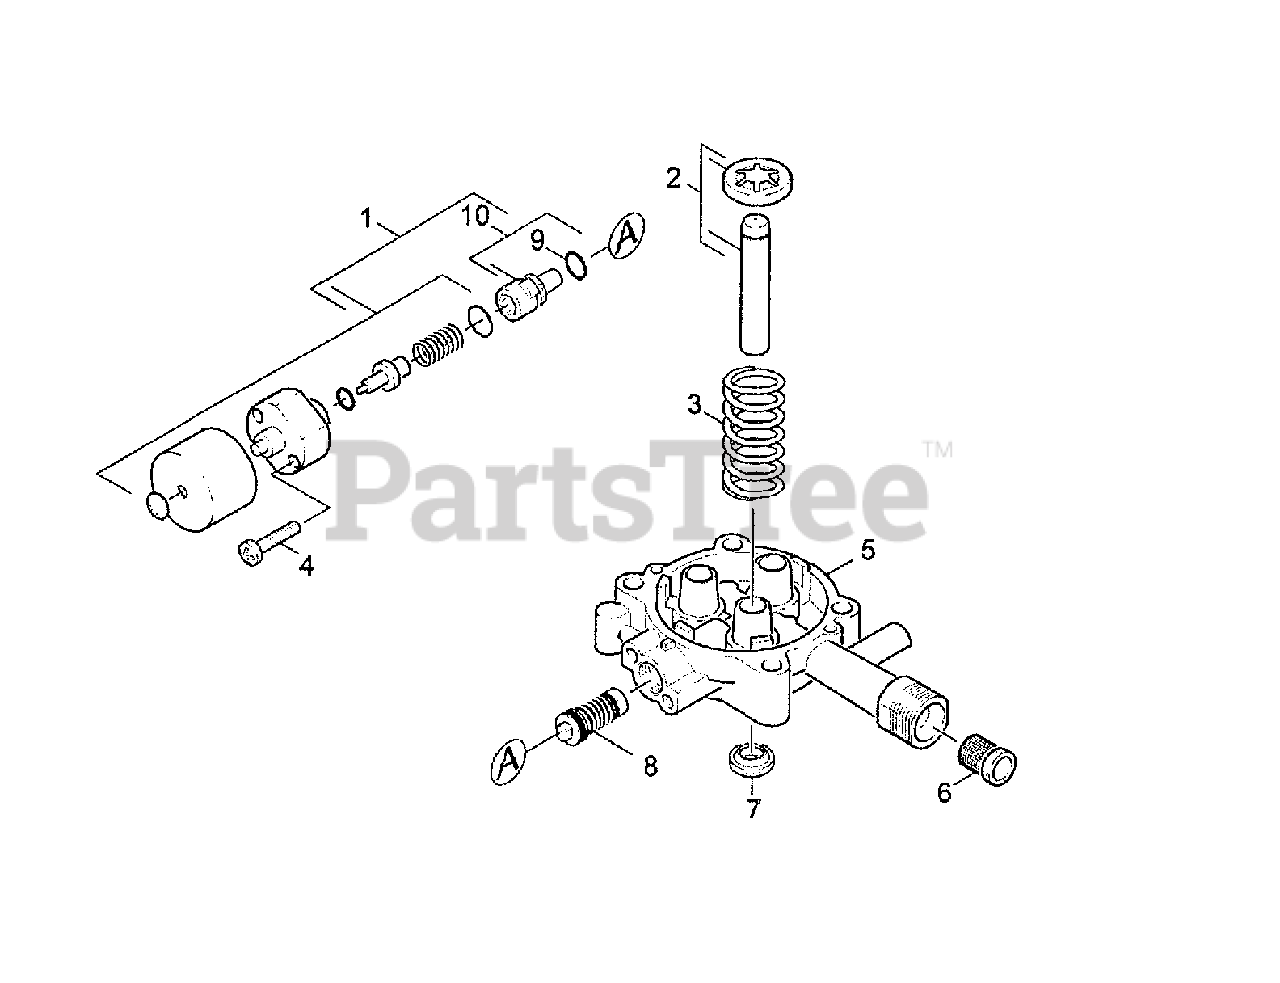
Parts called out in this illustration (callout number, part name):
3	Pressure Spring
5	Piston Guide
7	Grooved Ring
8	Spill Valve
